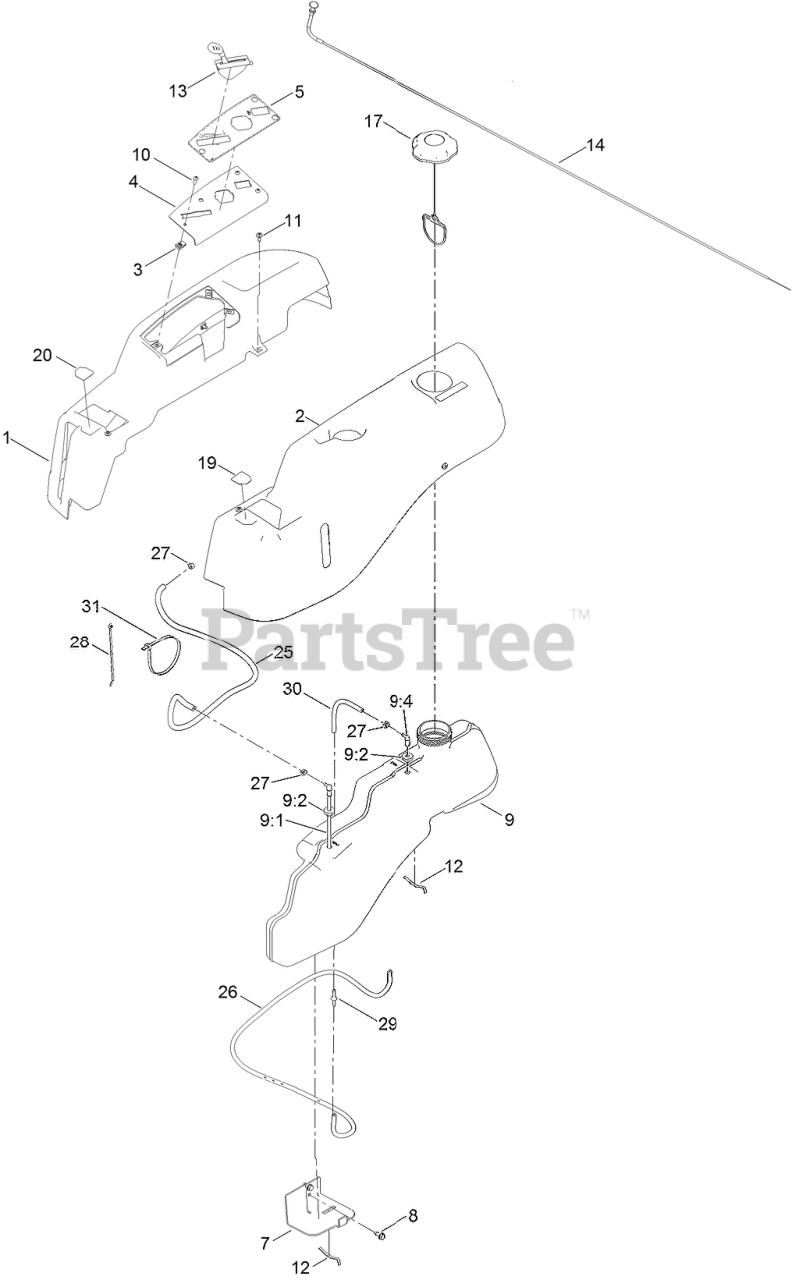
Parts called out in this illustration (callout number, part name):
1	POD-RH
2	POD-LH
4	PLATE-CONTROL
5	DECAL-PANEL, CONTROL
7	SUPPORT-TANK, FRONT
8	SCREW-HWHTF
9	FUEL TANK ASM
9:1	CONNECTOR-ELBOW, 90 DEG
9:2	BUSHING
9:4	FITTING-PLASTIC
10	SCREW-PRH
11	SCREW-SHOULDER
12	SPRING
13	CABLE-THROTTLE
14	CABLE-CHOKE
17	CAP-FUEL, RATCHETING
19	DECAL-LEVER, CONTROL (LH)
20	DECAL-LEVER, CONTROL (RH)
25	HOSE-FUEL
26	HOSE-FUEL
27	CLAMP-HOSE
29	ADAPTOR-ORIFICE
30	HOSE-FUEL
31	TIE-CABLE
